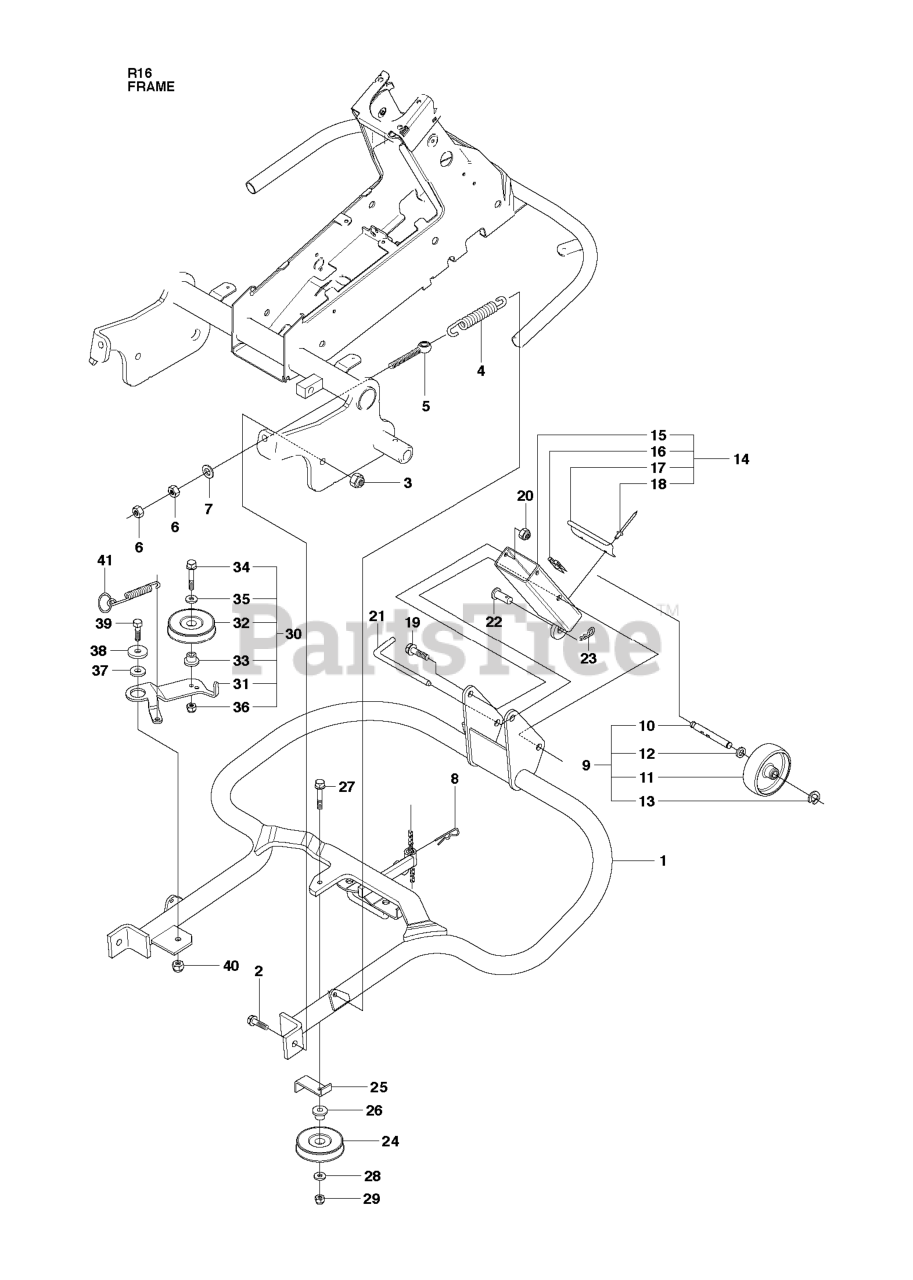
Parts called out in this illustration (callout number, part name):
6	NUT
7	WASHER
9	WHEEL ASSY
13	RETAINING RING
20	LOCKNUT M8
29	LOCKNUT M8
30	BELT TENSIONER ASSY
36	LOCKNUT M8
40	NUT
